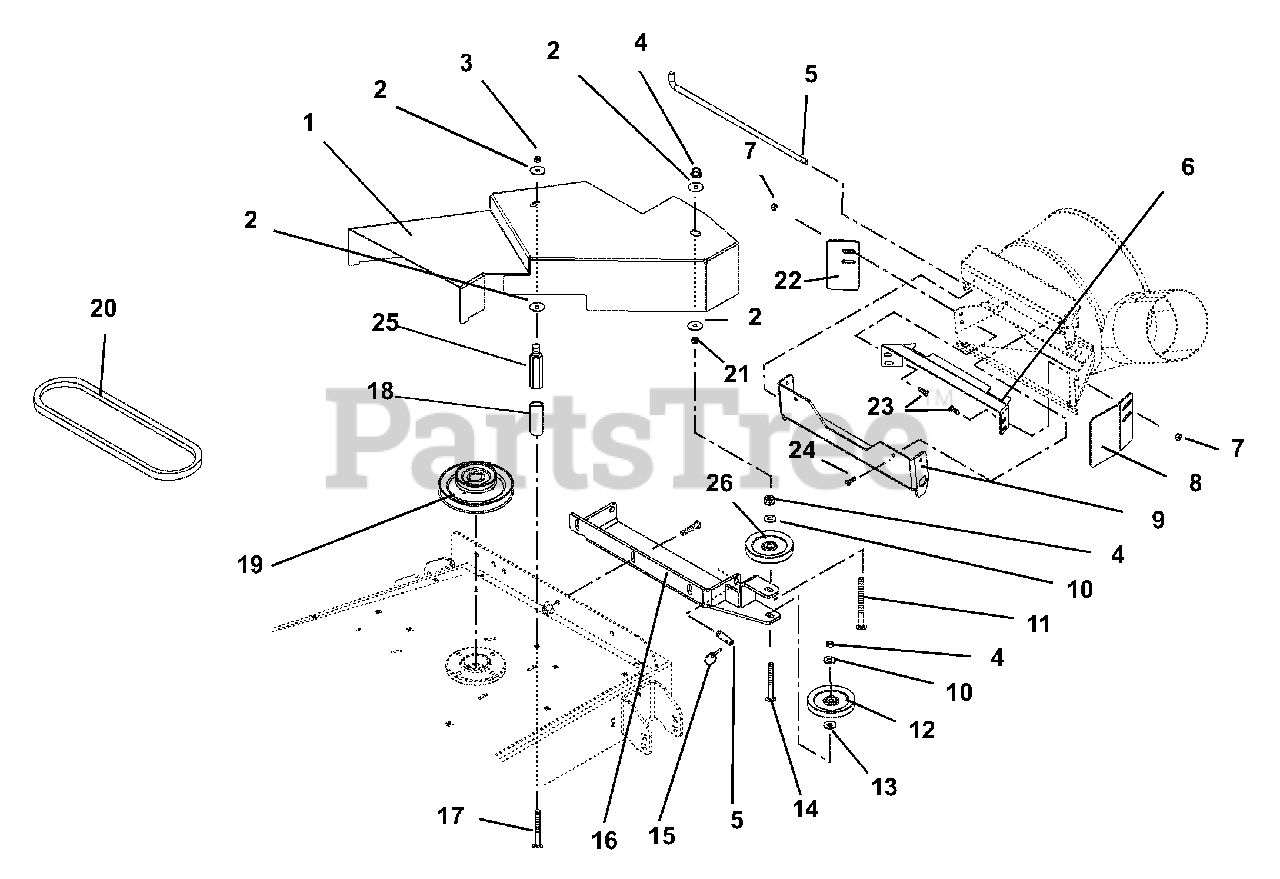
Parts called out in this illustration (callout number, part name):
1	Weldment, Belt Guard
2	Washer-Flat-Steel .38 x 1.50 x .062
3	Nut-Locking-Nylon .312-18
4	Nut-Locking-Nylon .38-16
5	Rod-Pivot
6	Guard, Pump Inlet
7	Nut-Locking-Top-Flange .25-20
8	Bracket, Formed
9	Weldment, Blower Mount
10	Washer-Flat-Steel .438 x 1.00 x .083
11	Bolt-Round Head Square Neck .38-16 x 2.5 Grade 5
12	Idler-V, 4.00 x .38
13	Washer-Flat-Steel .406 x 1.00 x .188
14	Bolt-Round Head Square Neck .38-16 x 1.75 Grade 5
15	Pin-Klik 1.00 x .188 x 1.25
15	(Gravely Part Number)
16	Weldment, Pivot Mount Bracket
17	Bolt-Round Head Square Neck .31-18 x 2.0 Grade 5
18	Tube .380 x .625 x 1.26
19	Pulley, Double V 3.50/5.25 Dia.
20	V-Belt, 48-780 78" Outer Circle)
21	Nut-Hex-Jam .375-16
22	Bar, Extension
23	Bolt-Round Head Square Neck .25-20 x .75 Grade 5
24	Screw-Tapping .25-20 x .50 Hex Washer Head Thread Rolling
25	Standoff, 2.75 x 5/16-18
26	Idler, Flanged 3.50
